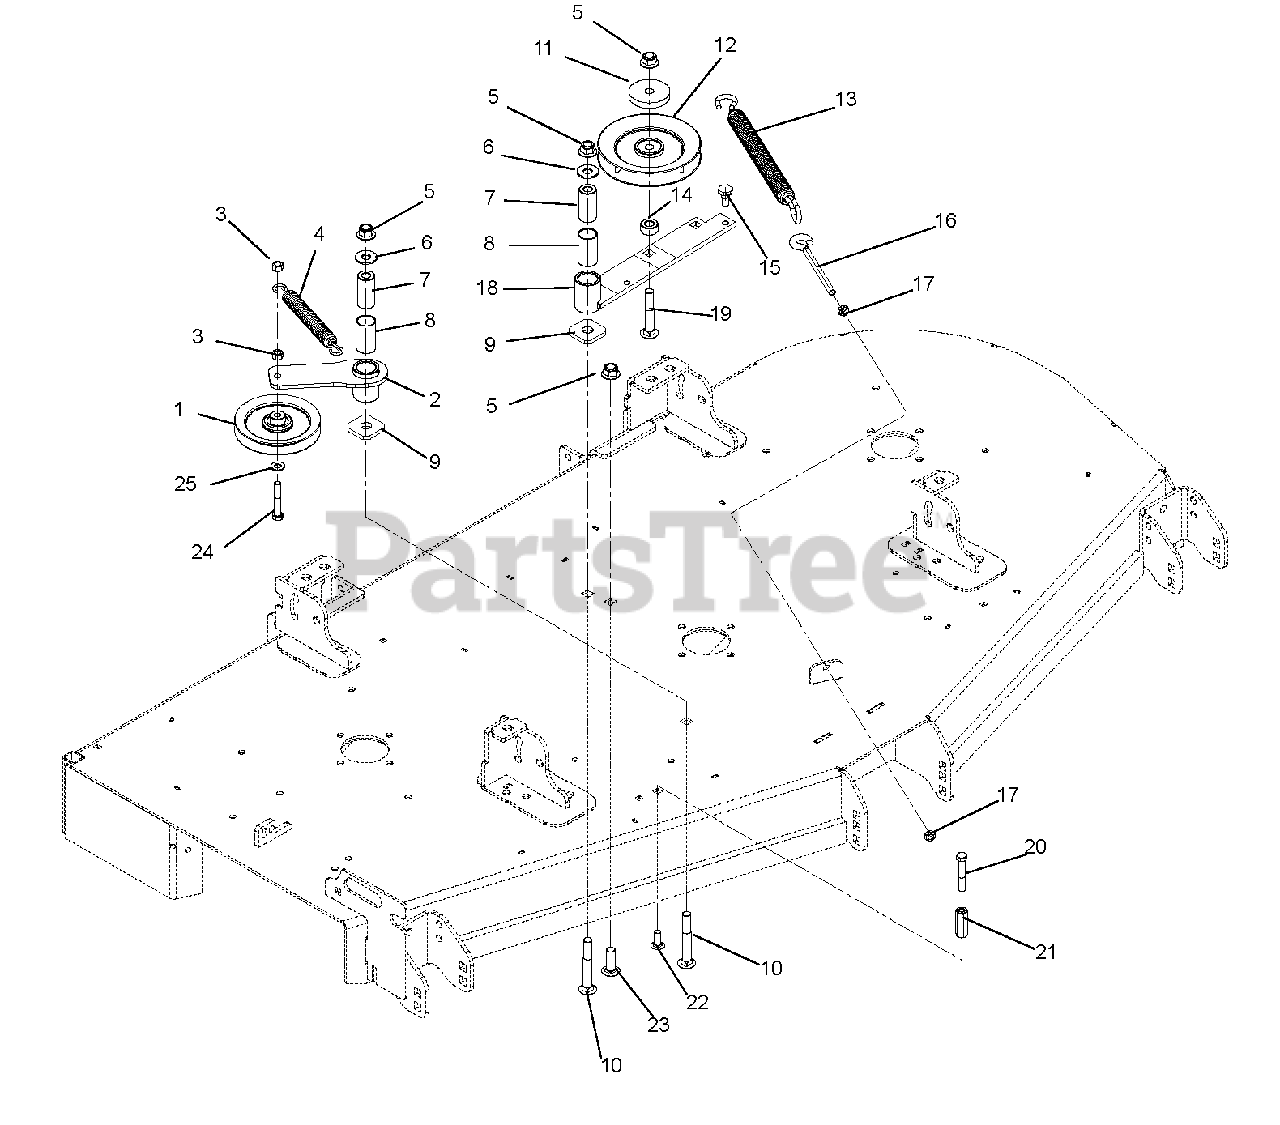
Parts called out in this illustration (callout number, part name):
1	Sheave, .38"ID x 5.00"OD V-Idler
2	Weldment, Idler Arm
3	Nut, Locking-Center .38-16
4	Spring, Extension
5	Nut, Locking-Nylon-Flange .50-13
6	Washer, Flat-Steel .563 x 1.38 x .109
7	Bushing, Spacer .505/.500 x .999/.996 x 2.05/2.03
8	Bushing, 1.00 x 1.125 x 1.936
9	Washer, Flat .640 x 1.75 x .250
10	Bolt, Round Head Square Neck .50-13 x 3.50 Grade 5
11	Cap, Idler Bearing Sealing
12	Sheave, .50"ID x 6.00"OD V-Idler
13	Spring, Extension
14	Bushing, Spacer .502 x .997 x .50
15	Bolt, Shoulder EP .38-16 x .30 Hex
16	Bolt, .38-16 x 5.50 .62 Diameter Eye
17	Nut, Hex-Jam .375-16
18	Weldment, Idler Arm
19	Bolt, Round Head Square Neck .50-13 x 3.00 Grade 5
20	Bolt, Hex .38-16 x 1.75 Grade 5
21	Nut, Cupling .375-16 x 1.75
22	Bolt, Round Head Square Neck .38-16 x 1.00
23	Bolt, Round Head Square Neck .50-13 x 1.50 FULL Thread Grade 5
24	Bolt, Hex .38-16 x 2.25 Grade 5
25	Washer, Flat-Steel .406 x .812 x .065
